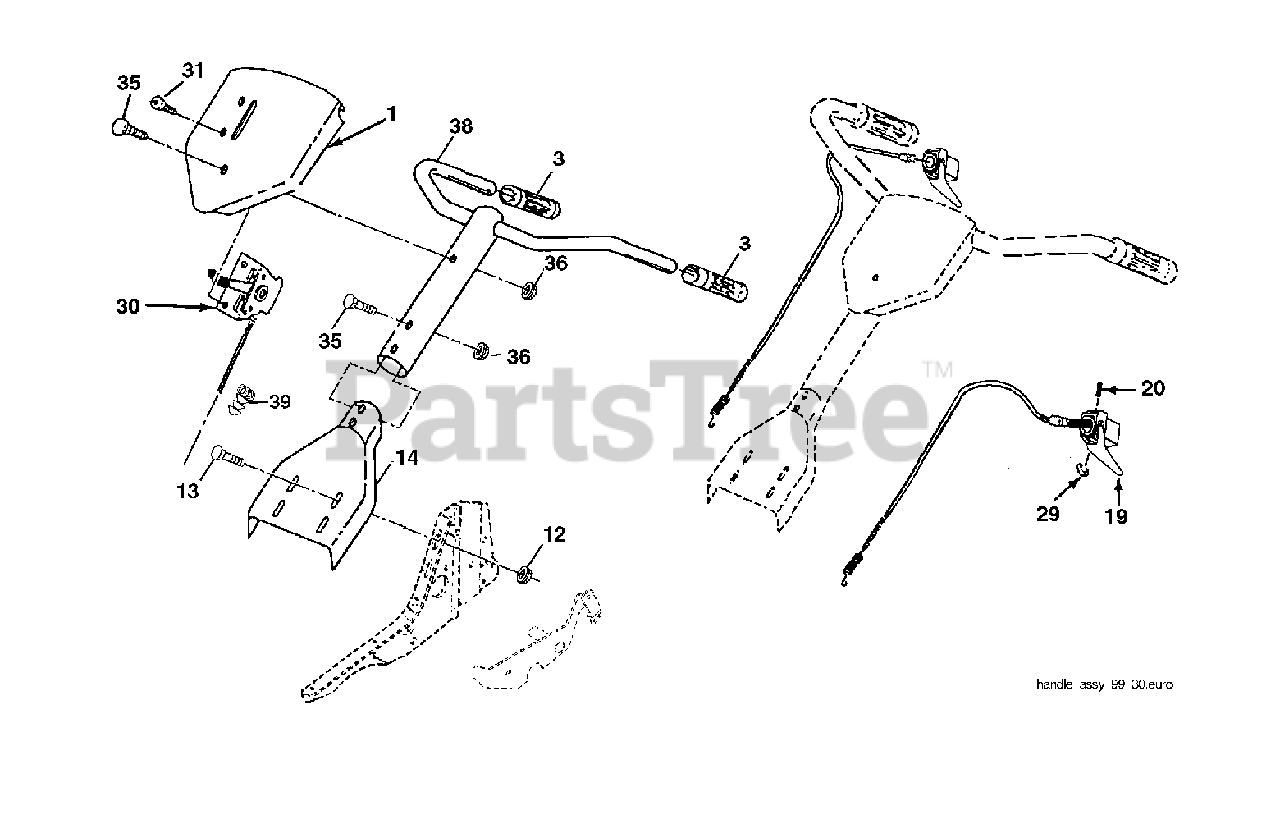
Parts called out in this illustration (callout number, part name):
12	NUT
13	BOLT.RH.SQNK.5/16
14	PANEL ASM. POLE
20	PIN, PIVOT
29	RETAINING RING
31	SCREW
35	BOLT.5/16-18X2.5
36	LOCKNUT-FLANGE 5/16-18
39	CLIP.ROUTING DUAL
